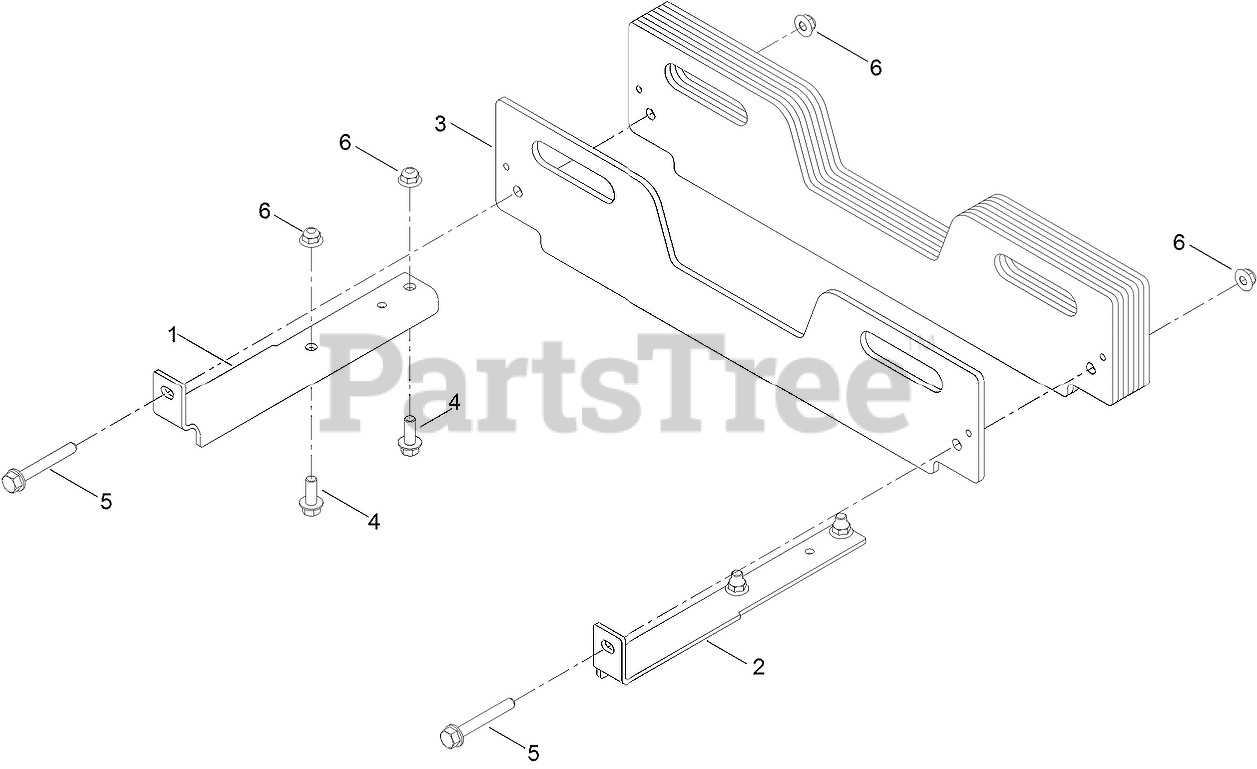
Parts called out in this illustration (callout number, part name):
1	BRACKET-WEIGHT, RH
2	BRACKET-WEIGHT, LH
3	WEIGHT-BAGGER
4	SCREW-HHF
5	SCREW-SPCL
6	NUT-HF, NI
